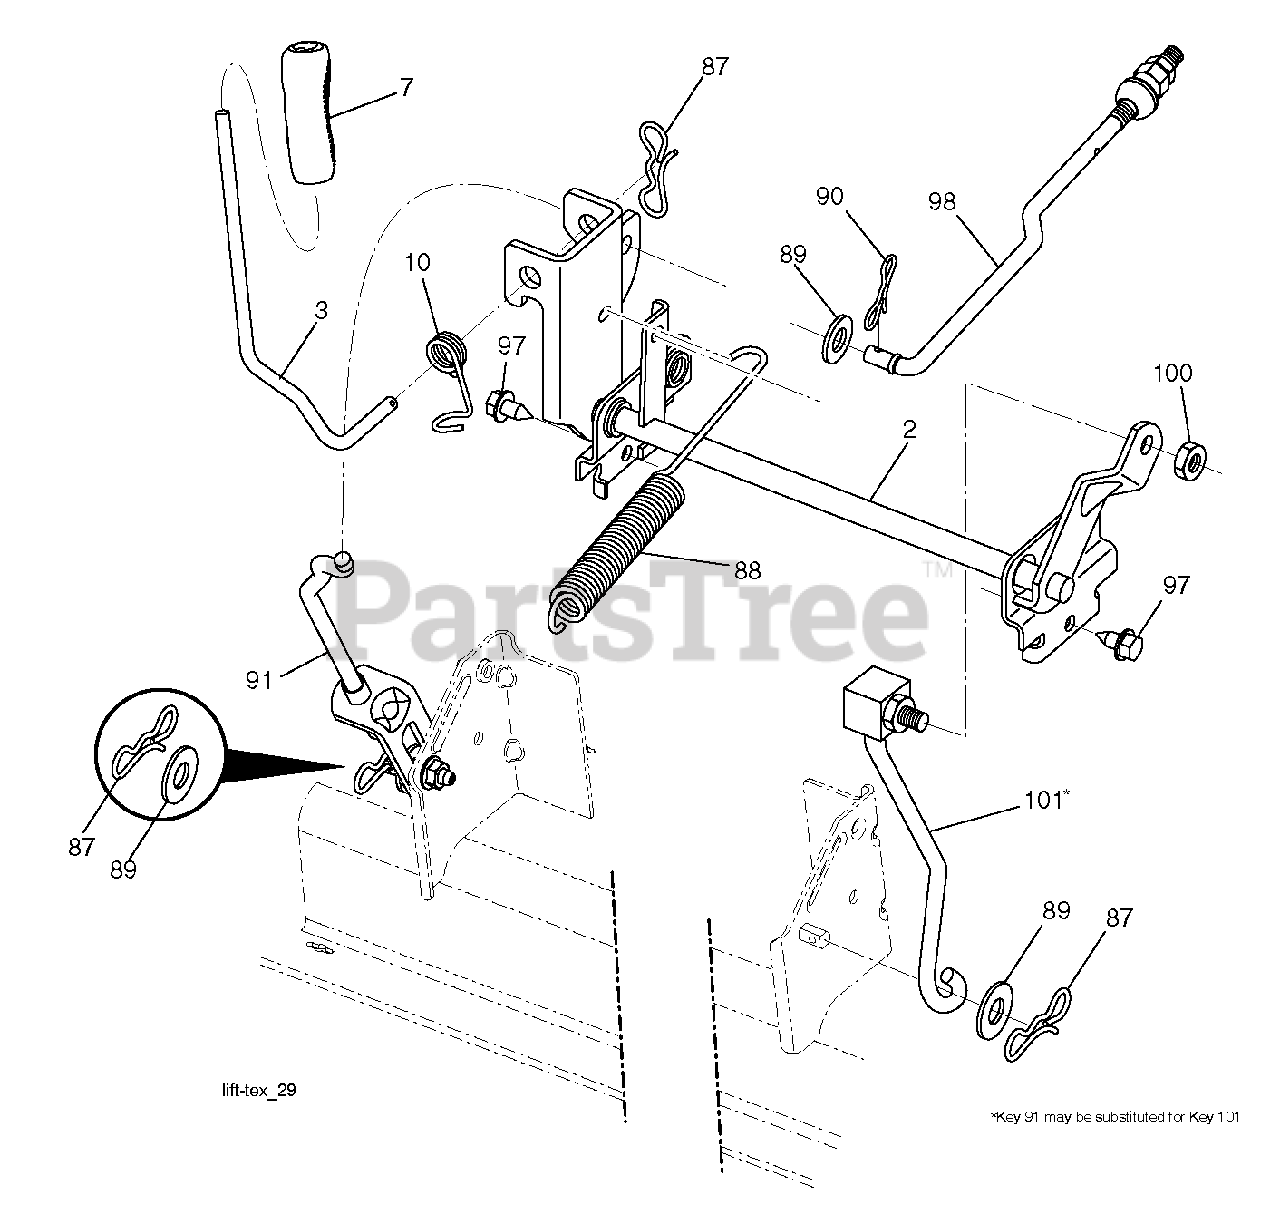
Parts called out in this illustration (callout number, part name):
2	SHAFT.ASM.CROSS.LIFT
3	LEVER.LIFT.HANDLE.GT
7	GRIP.HANDLE.LIFT.PVC.BLACK
10	SPRING.TORSION.LIFT.HANDLE
87	PIN.COTTER.7/16.BOW TI.
88	SPRING.LIFT.ASSIST.GT2
89	WASHER.CLEAR.ZINC
90	PIN.COTTER.5/16.BOW TI
91	LINK.ASM.LIFT.REAR
97	SCREW 3/8-16X3/4
98	LINK.ASM.SUSP.FRONT.MW
100	LOCKNUT
101	LINK.ASM.LIFT.FIXE.38/42/46"
